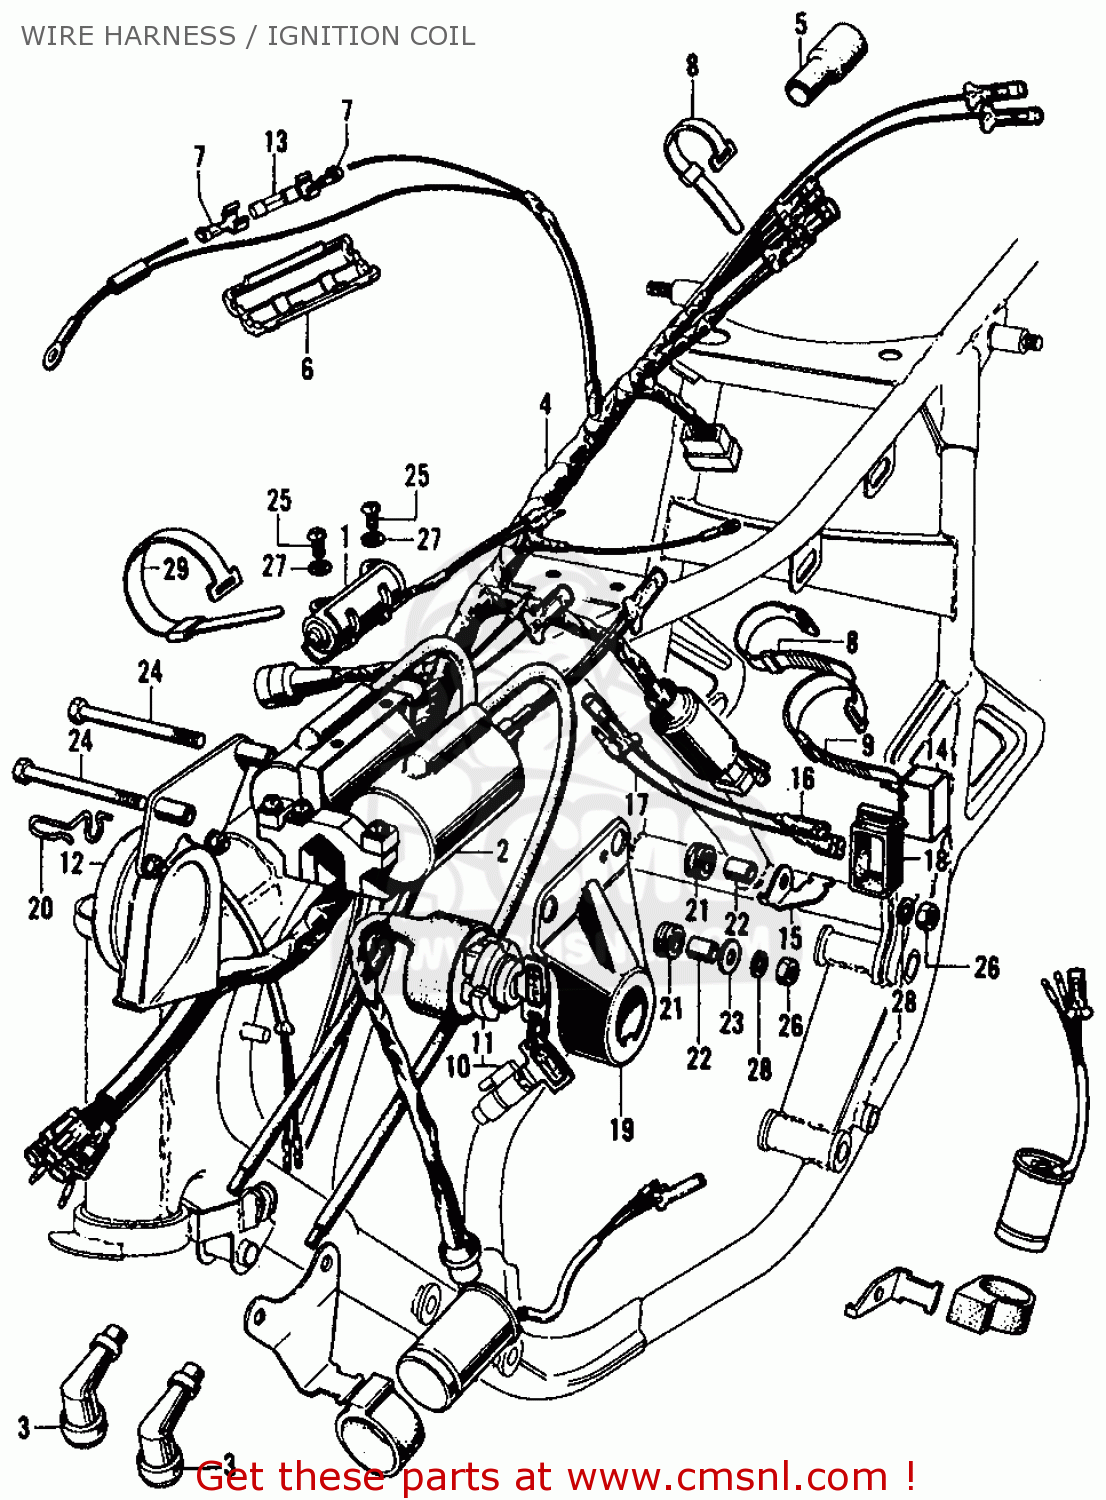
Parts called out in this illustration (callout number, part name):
1	CONDENSER ASSY
2	COIL IGNITION
3	CAP,SUPPRESER
4	HARNESS,WIRE
5	CONNECTOR,HARNESS
6	CASE,FUSE
7	CONNECTOR,FUSE
8	BAND,B1 WIRE
9	BAND,B1 WIRE
10	KEY-SET
12	HORN ASSY
13	FUSE,15A
14	SIGNAL STAT
15	STAY WINKER RELAY
16	CORD A WINKER
17	CORD B WINKER
18	SUSPENSION,RELAY
19	BRACKET SWITCH
20	CLAMPER CABLE
21	RUBBER,NU BRACKET
22	COLLAR NO BRACKET
23	WASHER,18MM
24	BOLT HEX 6X65
25	SCREW,CROSS 5X8
26	NUT HEX 6MM
27	WASHER,SPG.,5MM
28	WASHER,SPRING,6MM
